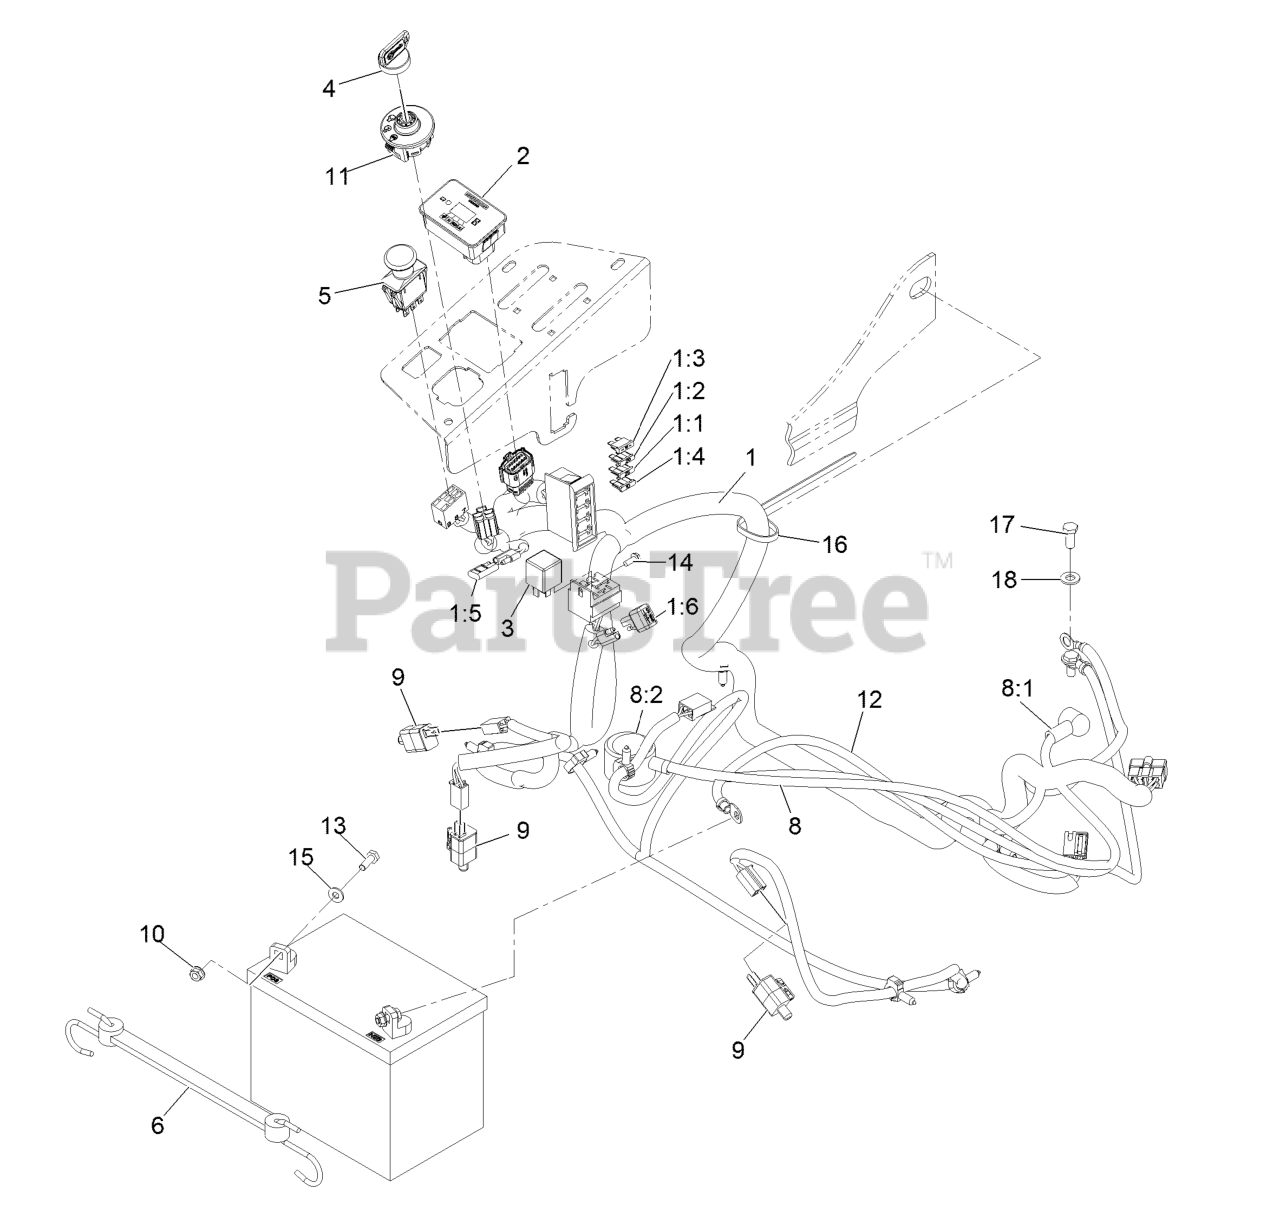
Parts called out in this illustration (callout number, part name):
1	HARNESS, WIRE
1:1	FUSE-BLADE, 25 AMP
1:2	FUSE-BLADE TYPE, 20 AMP
1:3	FUSE-BLADE, 15 AMP
1:4	FUSE-BLADE, 10 AMP
1:5	CAP-PLUG
2	MODULE ASM
4	KEYS-IGNITION (SPARE PAIR
4	KEY-IGNITION
5	SWITCH-PTO
6	HOLDDOWN-BATTERY
8	POSITIVE BATTERY CABLE AS
8:1	INSULATOR-SOLENOID
8:2	INSULATOR-BATTERY
12	CABLE-BATTERY, NEGATIVE
13	SCREW-HH
14	SCREW-TAPTITE
15	WASHER-FLAT
16	TIE-PLASTIC
17	SCREW-HH
18	WASHER-PLAIN
